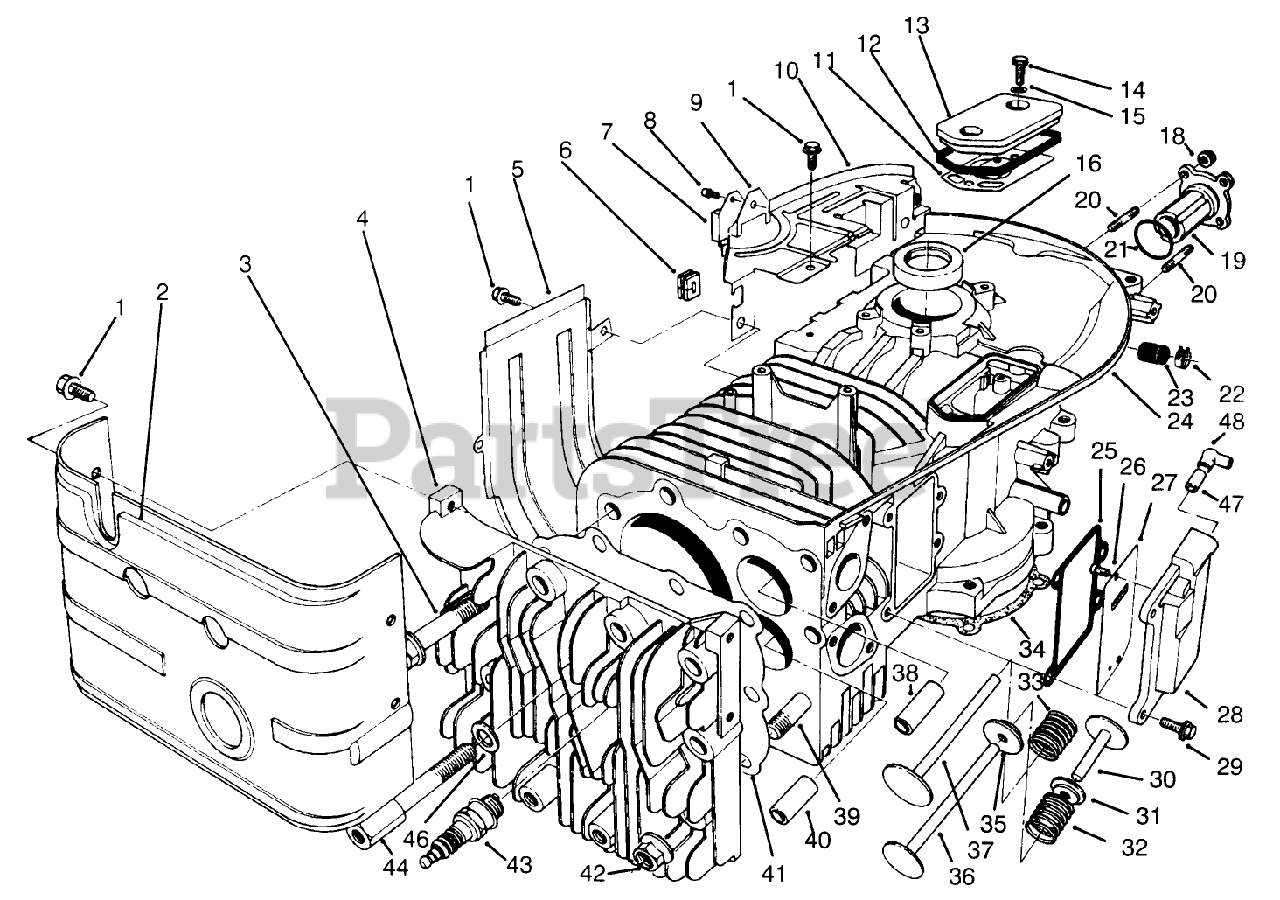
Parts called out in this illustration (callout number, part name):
1	Bolt-Flanged (6X10)
2	Shroud
3	Bolt
4	Cylinder Head
5	Shroud
6	Grommet
7	Igniter
8	Screw
9	Bracket
10	Fan Housing
11	Breather
12	Gasket
13	Cover
14	Bolt
15	Gasket
16	Seal-Oil
18	Nut
19	Shaft
20	Stud
21	O-Ring
22	Clip
23	Plug
24	Crankcase Assembly
25	Gasket
26	Screw
27	Cover
28	Cover-Valve Chamber
29	Bolt-Flanged (6X16)
30	Tappet
31	Retainer-Spring
32	Spring-Valve
33	Spring-Valve
34	Gasket
35	Rotator
36	Exhaust Valve
37	Intake Valve
38	Guide-Intake Valve
39	Stud
40	Guide-Exhaust Valve
41	Gasket
42	Nut
43	Spark Plug
44	Bolt
46	Washer
47	Tube
48	Joint
